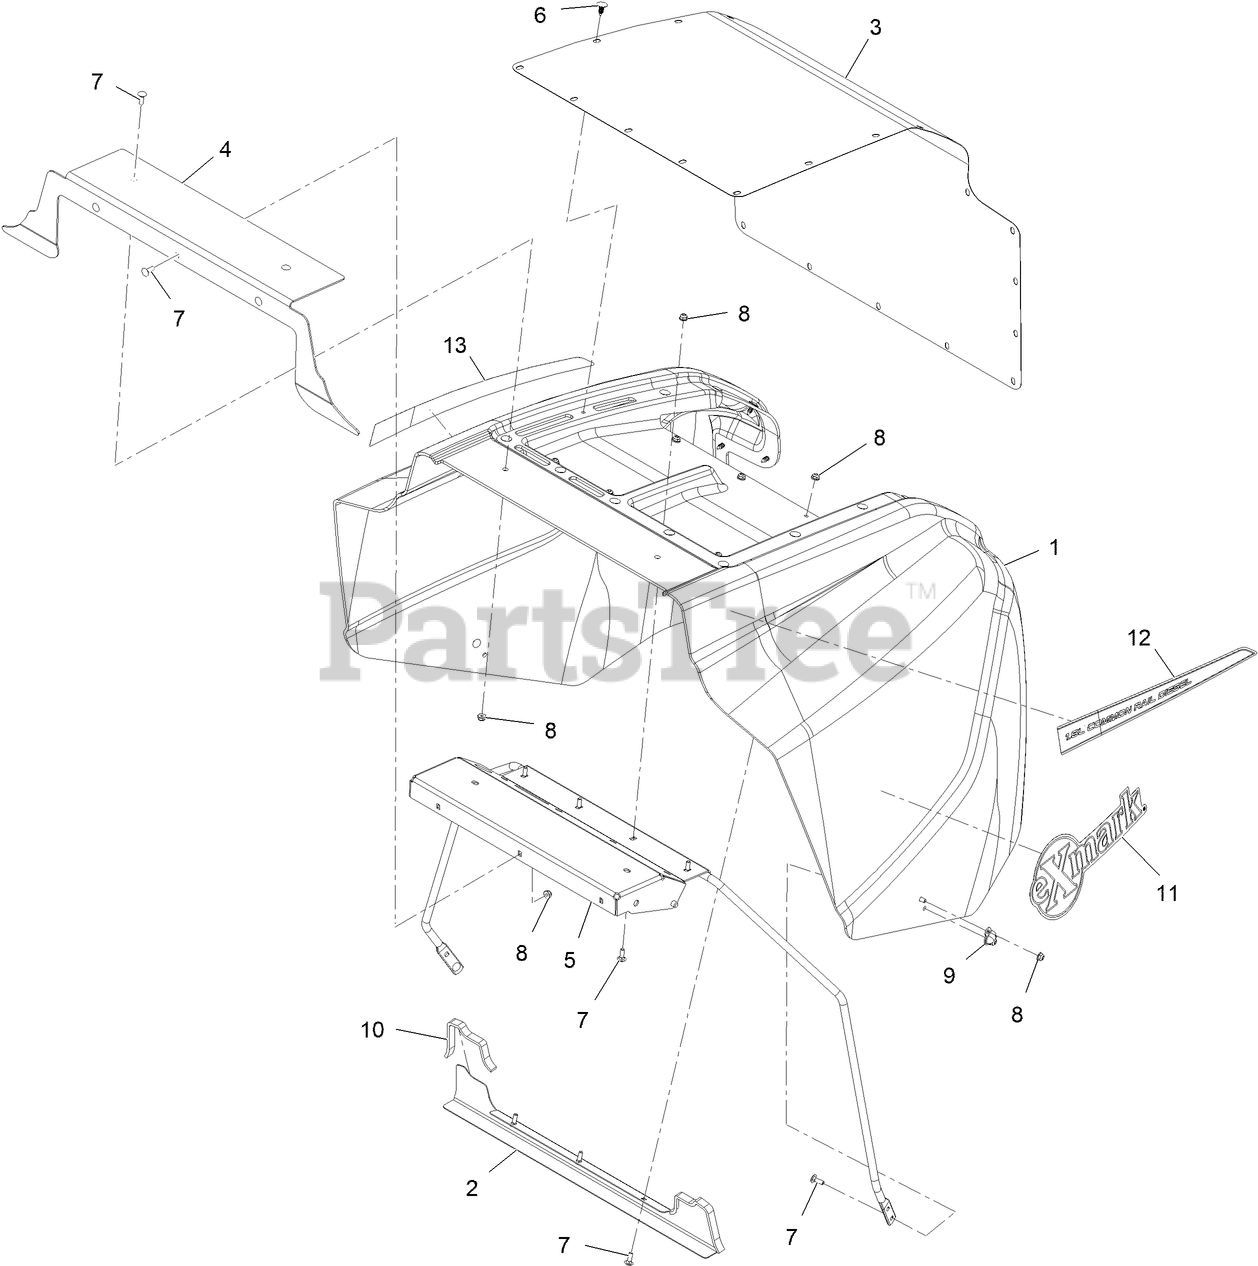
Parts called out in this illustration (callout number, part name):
2	PLATE-SEAL
4	BRACKET-HOOD BLOCK OFF
5	HOOD SUPPORT ASM [BLACK]
6	PLUG-PLASTIC
7	BOLT-CARR
9	LATCH, KEEPER
10	SEAL-FOAM
11	DECAL-EXMARK
12	DECAL-COMMON RAIL DIESEL-LH
13	DECAL-COMMON RAIL DIESEL-RH
